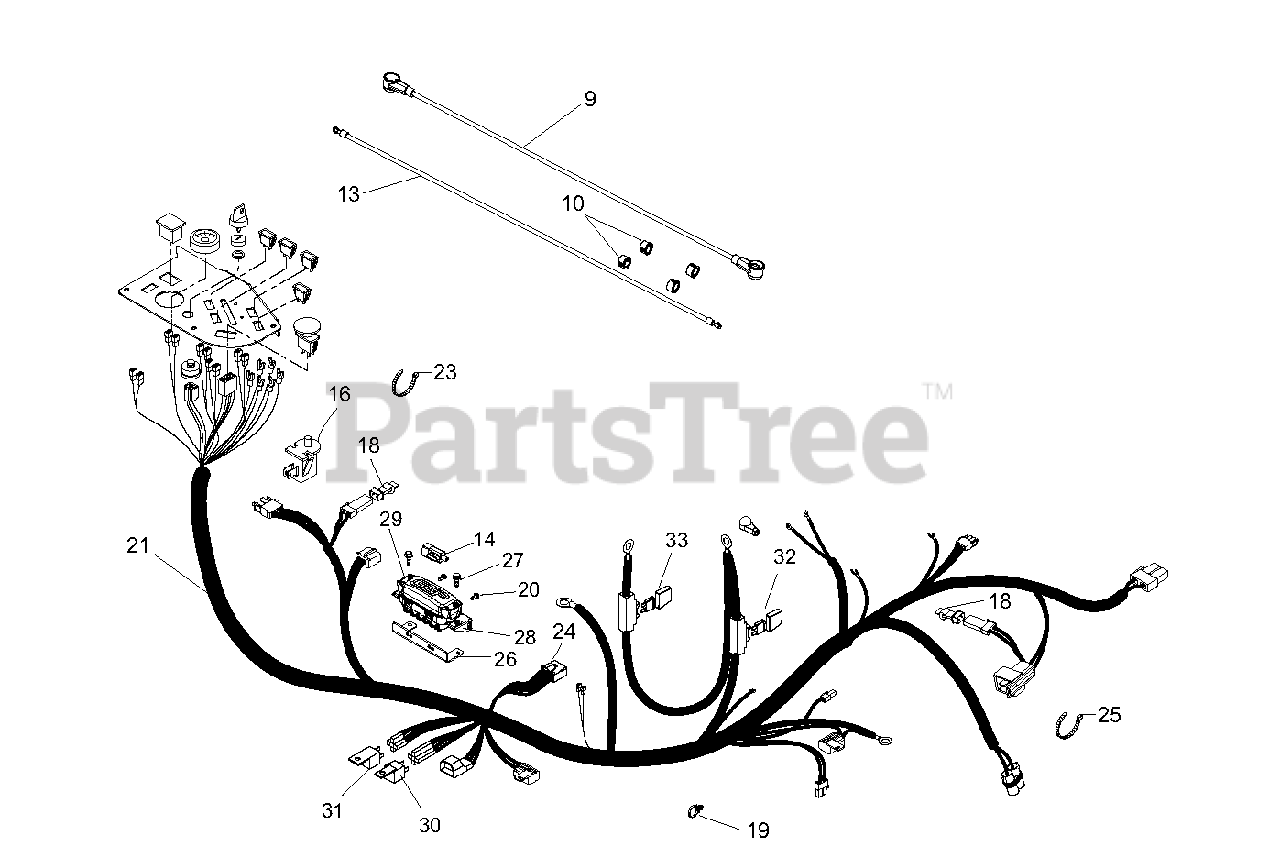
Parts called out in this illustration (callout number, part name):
9	Cable, POS Bettery W/Boots 4 x 48
10	Bushing, Panel Snap .687 x .875 x .56
13	Cable, Negative Battery 49.0"
14	Switch, Snap-In -N.O./N.O.
16	Switch, Snap Mounting (Included with Seat)
18	Diode, Connector Shell (Included with Harness)
19	Cable Tie with TREE (.25 HOLE)
20	Bolt, Hex M6-1.0x25
21	Harness, PT400 Diesel Wiring
23	Cable Tie
24	Module, Interlock, Delay (included with Harness)
25	Cable Tie
26	Fuse Holder Mounting Bracket
27	Screw- Tapping .25-20X.50 Hex Washer Head
29	Cover, Fuse Holder
30	Relay, 70A (included with Harness)
31	Relay, Sealed w/Diode (included with Harness)
32	Fuse, 40A Slow-Burn Maxi (included with Harness)
33	Fuse, 70A MAXI
34	Glow Plug Timer Module (included w/engine)
